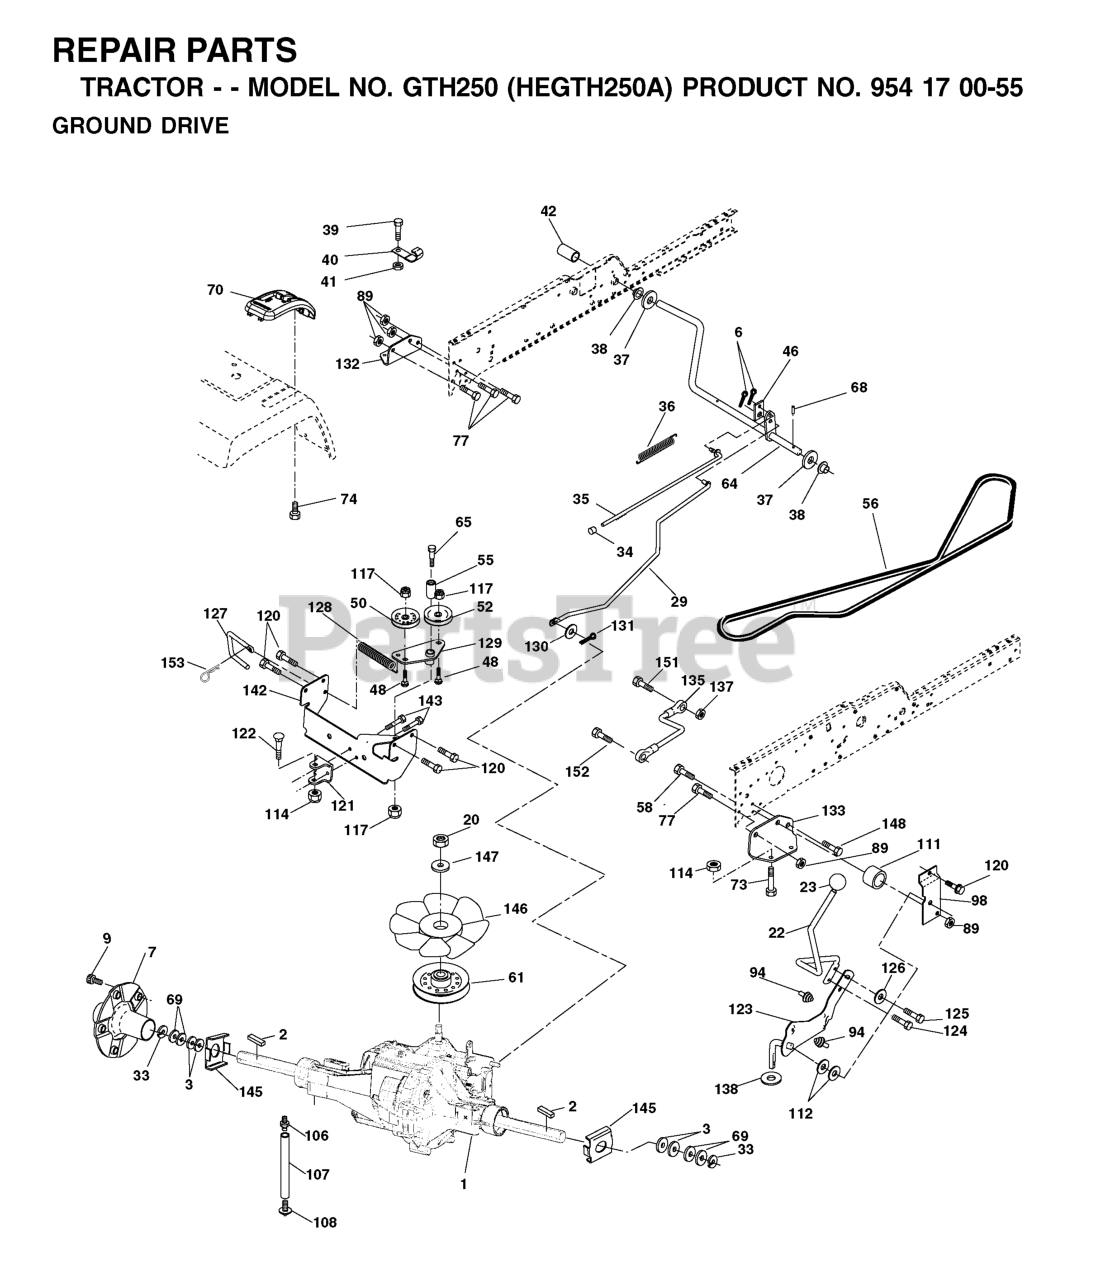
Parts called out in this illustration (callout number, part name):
2	Key Sq. 1/4 x 1/4 x 2.375
6	COTTER PIN
7	HUB ASMBLY
20	NUT.HEX.1/2-20
22	LOWER SHIFT LEVER ASM
23	KNOB.DELUXE.(PISTOL.GRIP).BLAC
29	BRAKE, ROD
33	E RING HYT
34	PLUNGER CAP
35	PARKING BRAKE ROD
36	SPRING DRIVE GROUND
39	Screw, Fin. #10-24 x 1
40	ACTUATOR INTERLOCK SWITCH
41	Nut Centerlock 10-24 unc
42	PEDAL COVER
46	RETAINER SPRING
50	FLAT IDLER PULLEY
52	IDLER PULLEY
55	BEARING LT (2 2)
56	BELT, V GROUND DRIVE
58	BOLT.HEX.7/16-14.FINISHED
61	PULLEY, TRANSAXLE
64	SHAFT.ASM.PEDAL.BRAKE
65	BOLT.SHLDR.3/8-16
68	ROLL PIN STD
70	CONSOLE AUTOMATIC YT.GT
73	BOLT HEX FLGHD 5/16-18X3 GR. 5
74	SCREW.HI-LO.CONSOLE
77	BOLT FIN HEX 7/16-14 X 1
89	Nut, Crownlock Hex 7/16-14 unc
94	FASTENER.XMAS.TREE
98	SHIFT BRACKET
106	O-RING KIT 70110
107	LINE.VENT.HYDRO-GEAR
108	CAP, VENT ASSY
111	SPACER SHIFT LEVER VGTH
112	WASHER NYLON HIGH TEMP
114	NUT.71038.31-18.HEX.NYLOCK
117	NUT LOCK FLG 3/8-16 UNC
120	SCREW 3/8-16X3/4
121	BRACKET STRAP TORQUE
122	Bolt RDHDSQ 5/16-18 Unc x 2-1/2
123	ROD, SHIFT
124	BOLT.SHOULDER.5/16-18X
126	WASHER.SRRTD.5/16
127	LINK CONTROL CLUTCH
128	SPRING DRIVE GRND
129	BRACKET ARM IDLER TENSIONING
131	COTTER PIN
132	BRACKET MTG HYDRO 3500 LH VGT
133	BRACKET MTG HYDRO 3500 RH VGT
135	LINK ASM CONTROL HYDRO 3500
137	LOCKNUT
138	THRUST WASHER
142	STRAP TORQUE HT-3500
143	SCREW 5/16"
145	WASHER.AXLE.FLANGE.HG-3000
146	FAN 7" HYDRO
148	SCREW.3/8-16
151	BOLT
152	BOLT HEX 5/16X1 W/PATCH
153	RETAINER M
